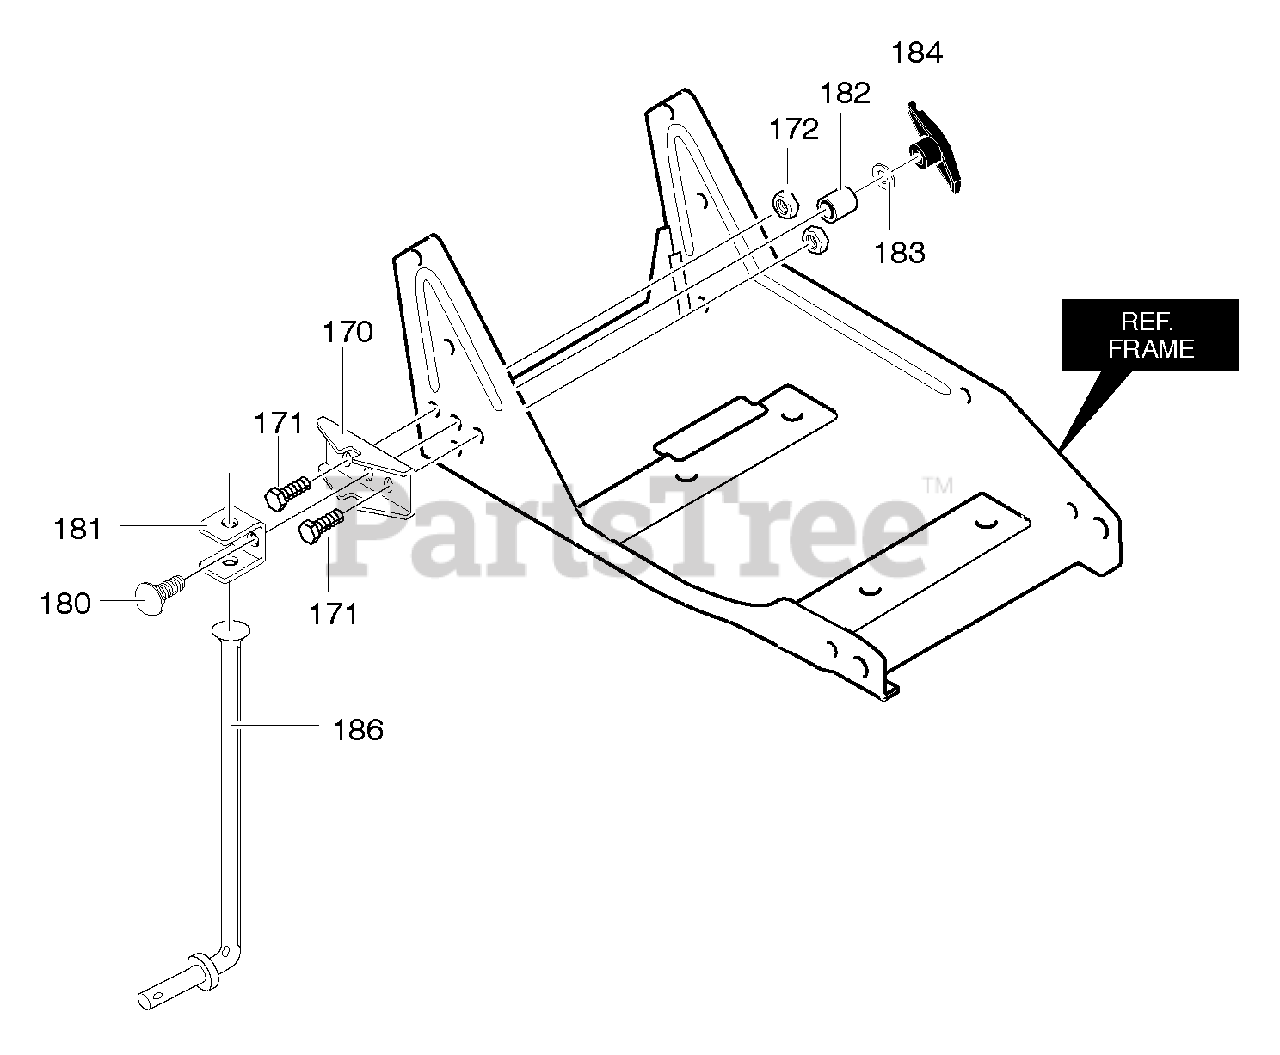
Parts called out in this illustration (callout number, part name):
170	Bracket, Curb Hop Mnt
171	Screw, 5/16-18 x 0.75
172	Nut, 5/16-18
180	Bolt, 5/16-18x2.00
181	Clevis
182	Spacer, Sleeve
183	Flatwasher
184	Knob, Wing 5/16-18
186	Rod, Wheel Support
